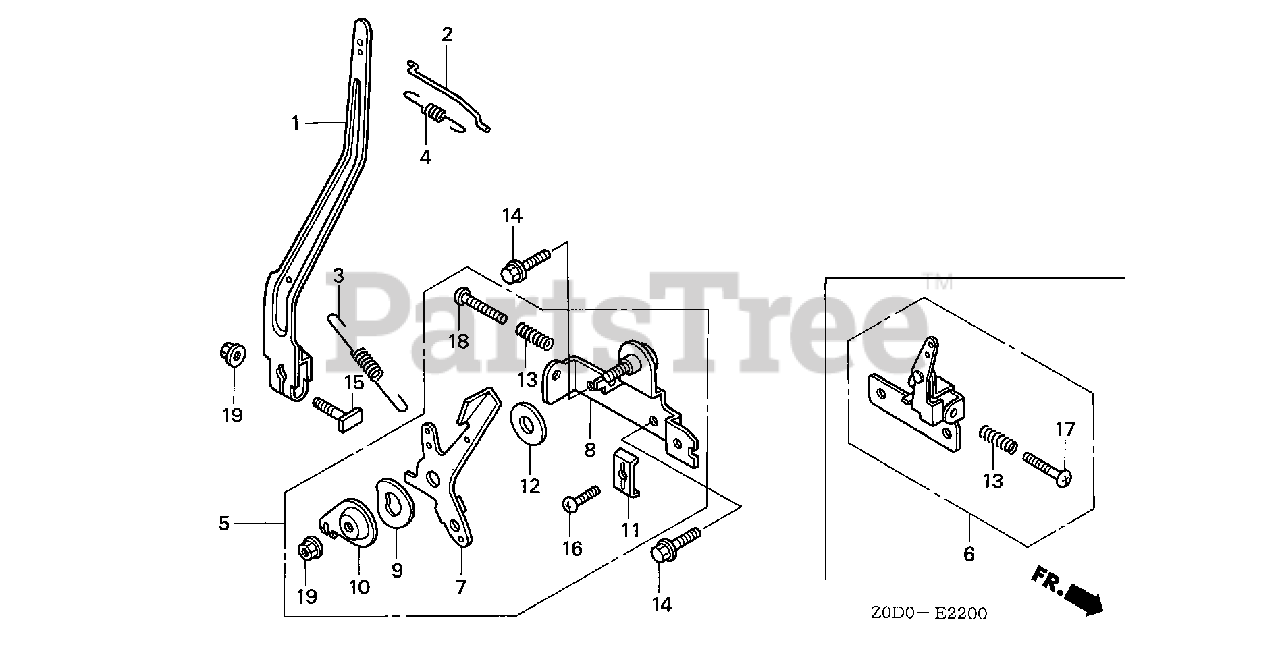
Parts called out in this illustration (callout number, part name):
1	ARM, GOVERNOR
2	ROD, GOVERNOR
3	SPRING, GOVERNOR
4	SPRING, THROTTLE RETURN
5	CONTROL ASSY. (STD)
7	LEVER, CONTROL (STD)
8	BASE, CONTROL (STD)
9	SPRING, LEVER
10	WASHER, CONTROL LEVER
11	HOLDER, CABLE
12	SPACER, CONTROL LEVER
13	SPRING, CONTROL ADJUSTING
14	BOLT, FLANGE (6X14)
15	BOLT, GOVERNOR ARM
16	SCREW, PAN (5X16)
18	SCREW, PAN (5X25)
19	NUT, FLANGE (6MM)
